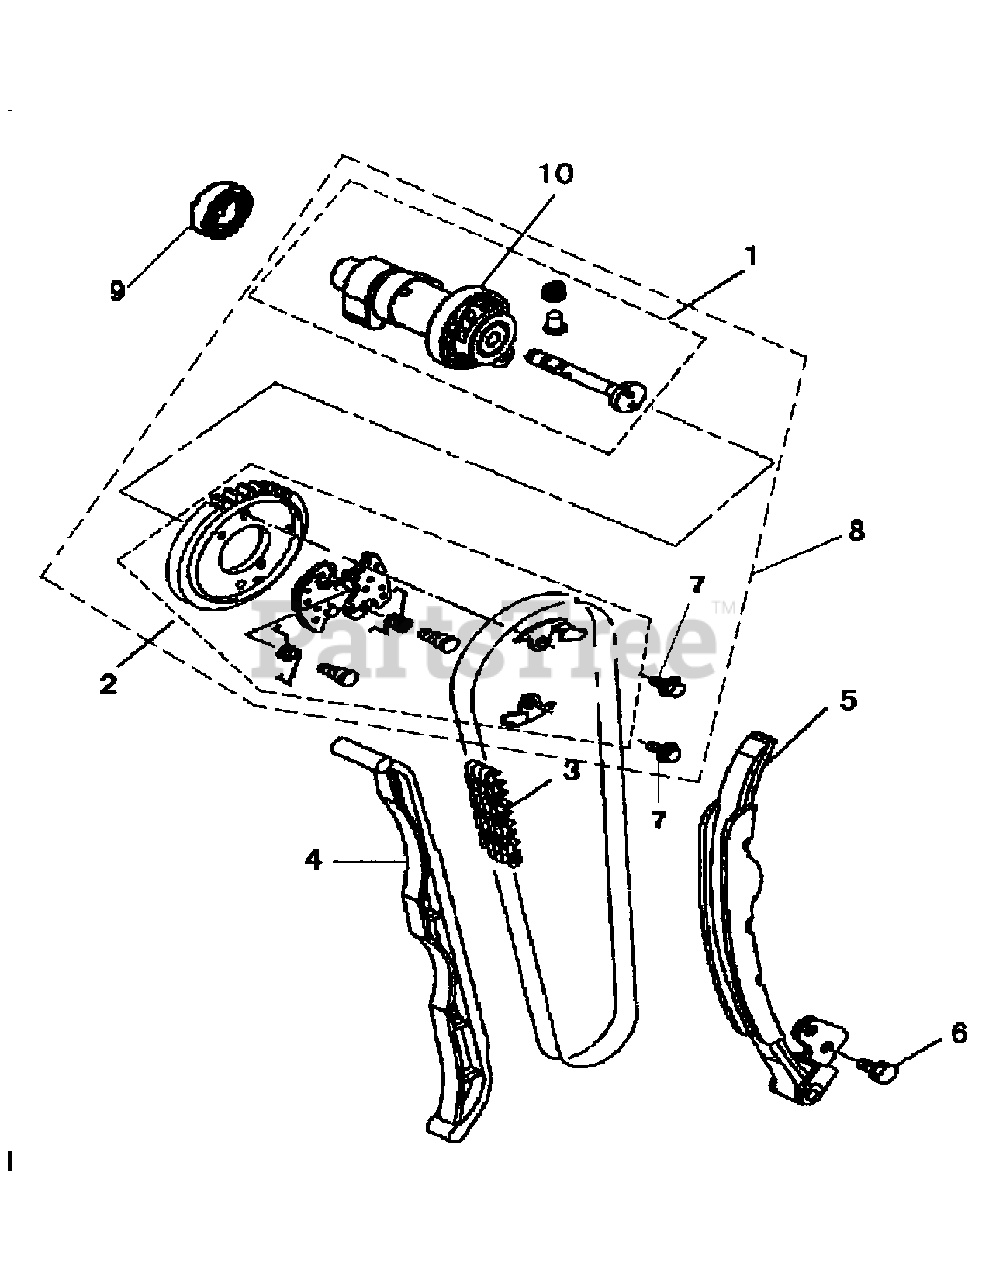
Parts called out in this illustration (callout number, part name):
1	Camshaft-Comp
2	Sprocket Asm-Timing
3	Timing Chain-M7-6.35-124
5	Tension Plate-Comp
7	Flange Bolt M7X11
8	Cam Shaft-Comp
